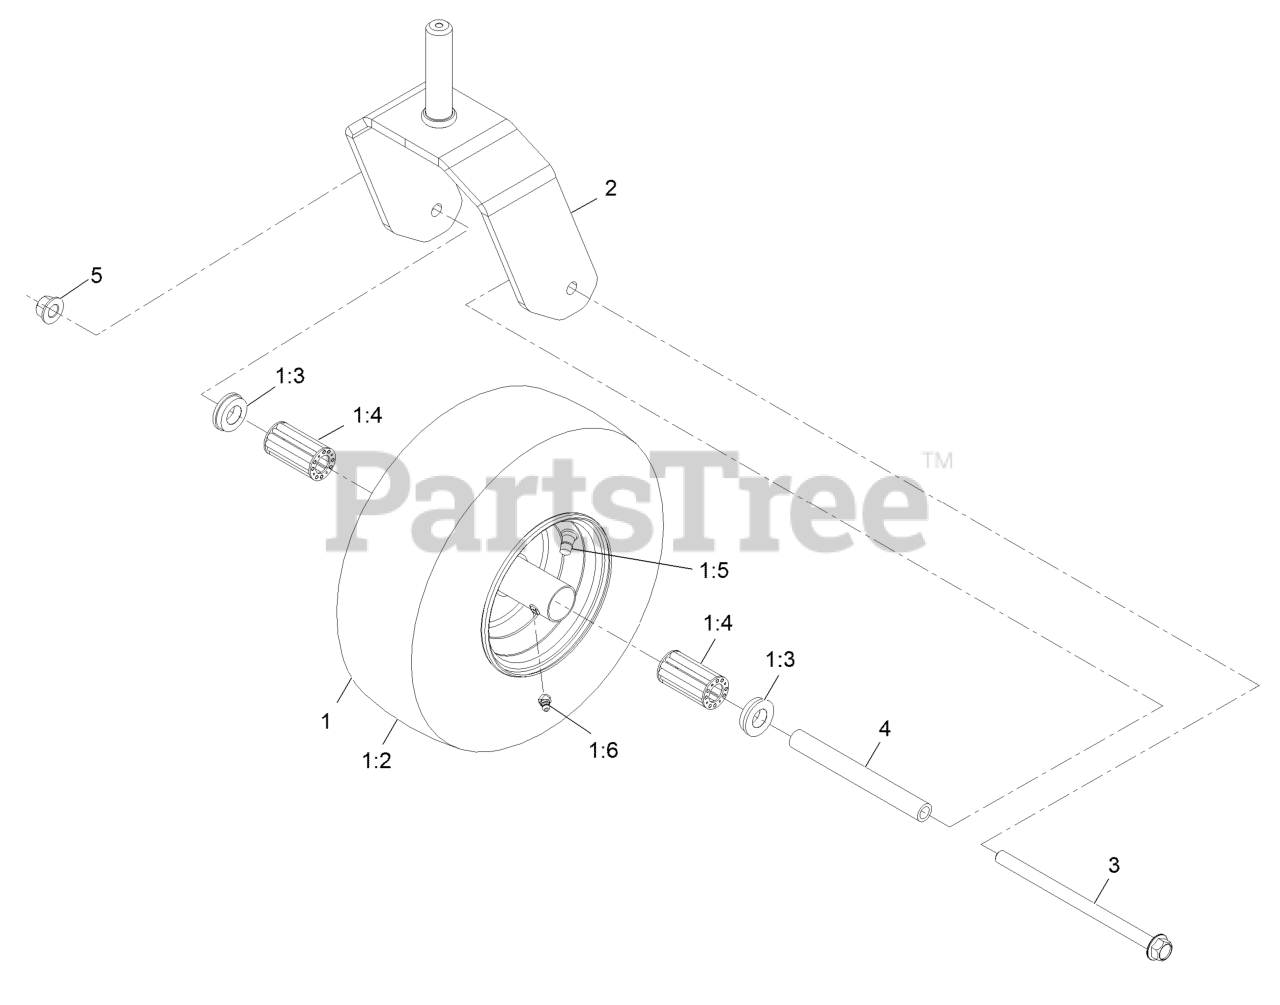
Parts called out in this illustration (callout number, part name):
1	ASM-Wheel And Tire 13X6.50-6
1:3	Bushing-Flange
1:4	Bearing-Roller, Wheel
1:5	Valve
1:6	Fitting-Zerk
2	Fork-Caster
3	Screw-HHF
4	Spanner-Wheel, Caster
5	Nut-Lock 1/2-13
